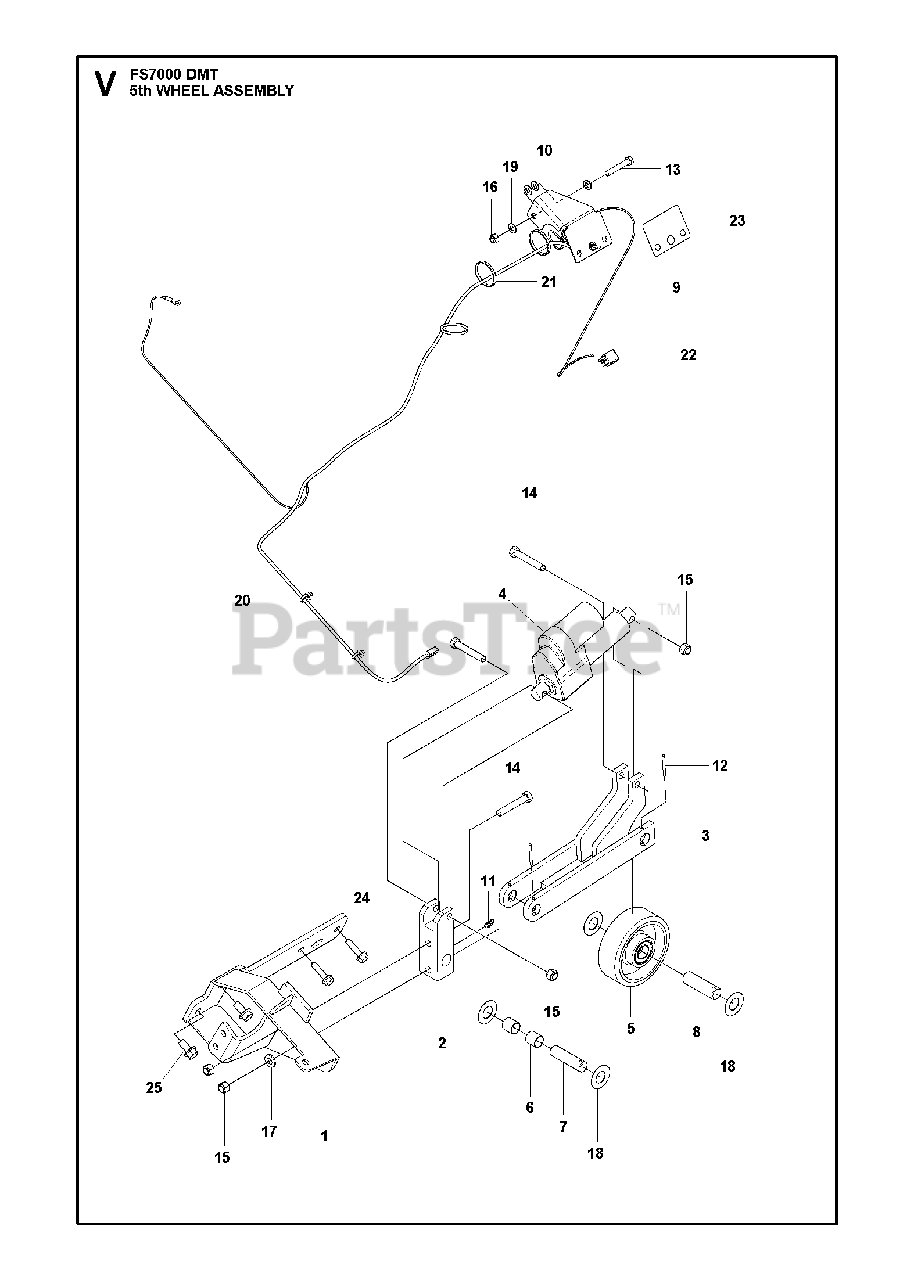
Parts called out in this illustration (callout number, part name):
15	NUT
16	HEXAGON LOCKING NUT
19	WASHER
